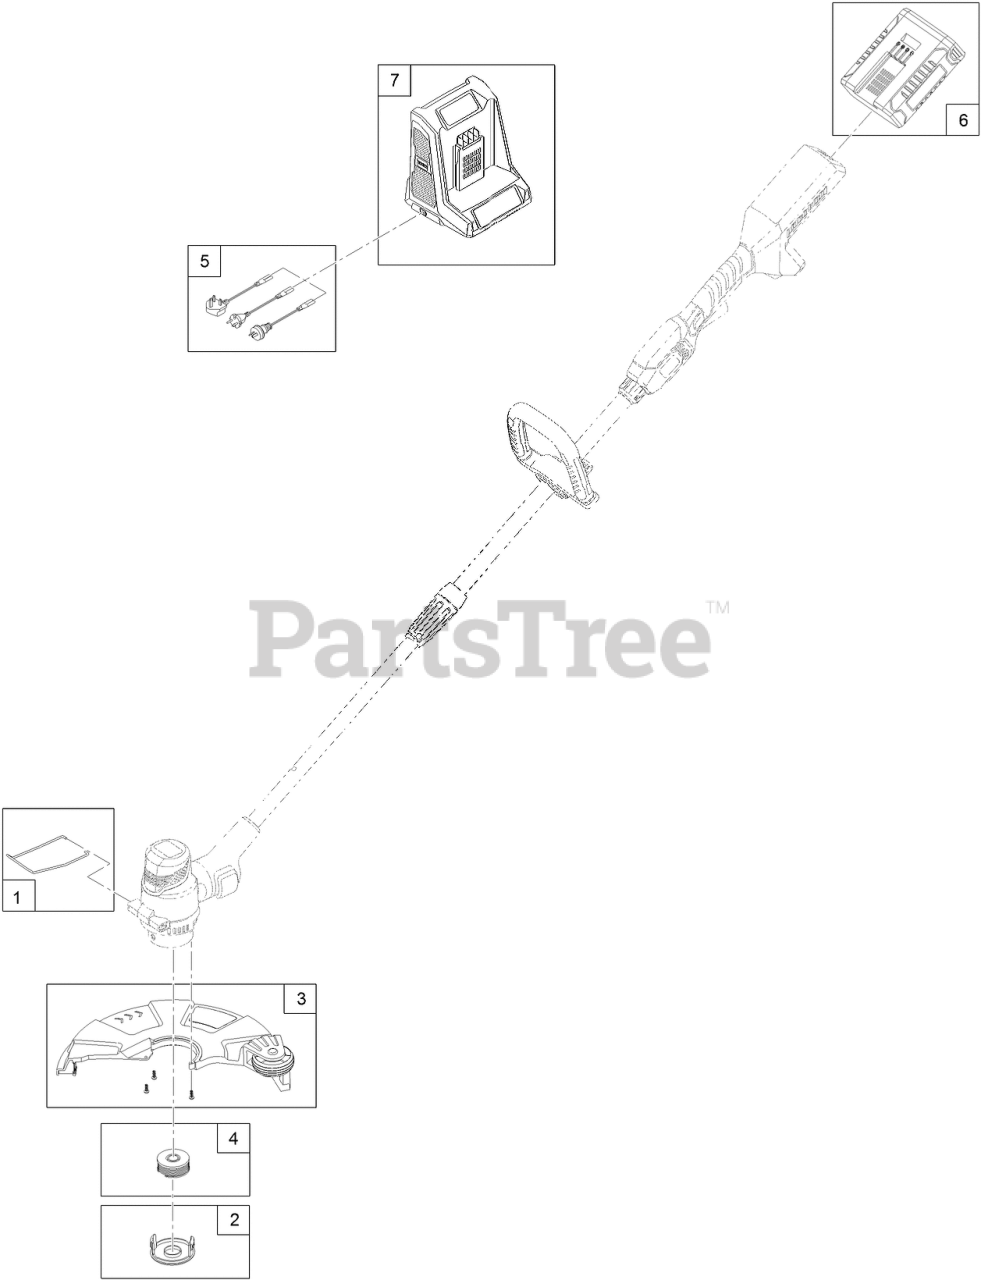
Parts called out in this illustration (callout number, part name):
1	CLIP-WIRE, GUIDE
2	CAP-RETAINER, SPOOL
3	GRASS SHIELD ASM
4	3-PACK SINGLE-LINE SPOOL
5	CORD SET
6	BATTERY-40V MAX
7	CHARGER-BATTERY, 40V MAX
